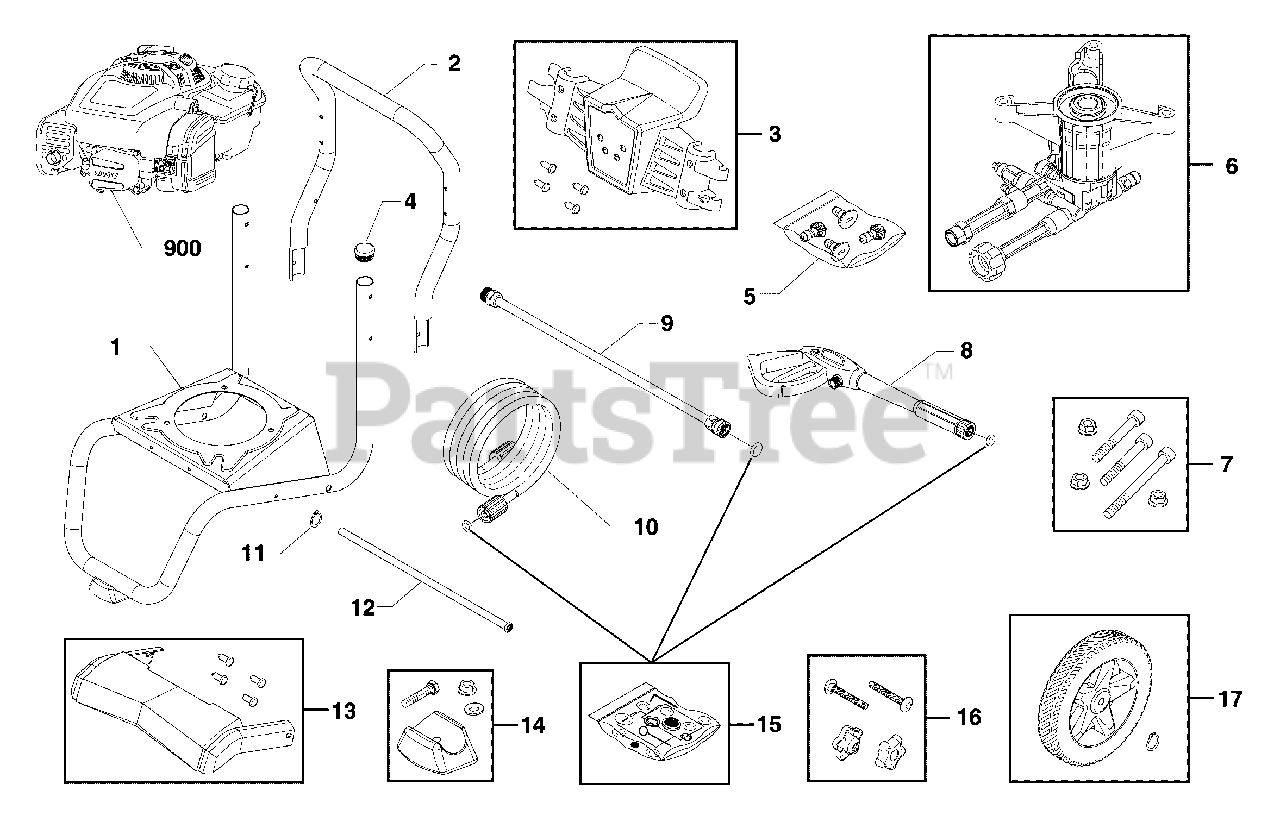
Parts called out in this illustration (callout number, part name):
5	Kit, Quick Connect Nozzles
7	KIT, Hardware, Pump Mounting
8	GUN
9	EXTENSION, QC
10	HOSE
14	MOUNT-VIBRATION
15	KIT-O-RING MAINTENANCE
16	KIT, Hardware, Handle
